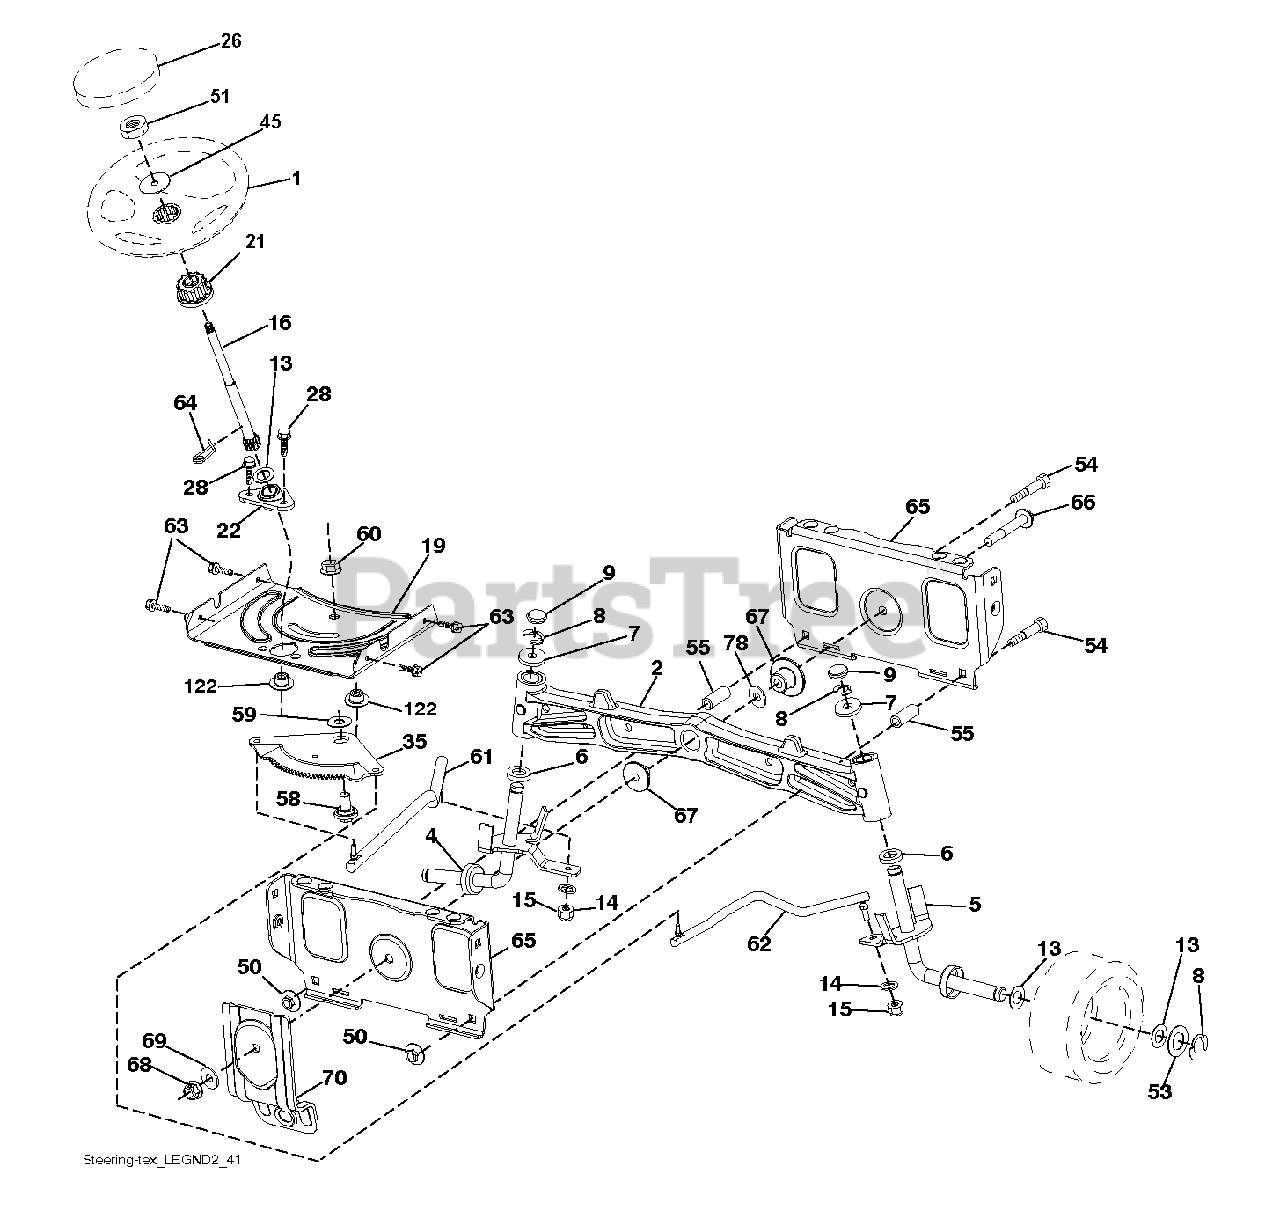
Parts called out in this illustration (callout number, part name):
1	WHEEL.STEER.HUSQ.SR.498.OVMLD
2	AXLE.CAST.IRON
4	SPINDLE.WELDED.LH.16"TEX
5	SPINDLE.WELDED.RH.16"TEX
6	THRUST WASHER
9	CAP.SPINDLE.BLACK
14	WASHER, LOCK 3/8
15	NUT CROWNLOCK 3/8-24
16	SHAFT, STEERING
19	PLATE.STEER.DDL.NLT/NG
21	ADAPTER, WHEEL STNG..
22	STEERING.SUPT.LOWER.
26	INSERT.CAP.WHL.STRG.HUSQ.PREM
28	SCREW, 3/8-16X3/4
35	GEAR.SECTOR.PLATE.DDL.
45	WASHER 9/16"ID, 2 3/8"OD
50	NUT LOCK FLG 3/8-16 UNC
51	NUT.HEX.1/2-20
53	WASHER.HARDENED
55	SPACER.BRACE.AXLE
58	BOLT.SHOULDER.SECTOR.P
59	WASHER.THURST.SECTOR.S
60	NUT FLANGE LOCK 5/8-11
61	DRAGLINK.LH.BALLSTUD.D
62	DRAGLINK.RH.BALLSTUD.D
63	SCREW
64	RETAINER.CLIP.SPRING.S
65	BRACE.AXLE.FRONT.NLT/N
66	BOLT HEX FGHD 7/16-14 X 3 SERR
67	BUSHING.PM.FRONT AXLE
68	NUT.LOCK.FLANGE.7/16
69	WASHER.1.5X.505X.118
70	BRKT.DECK.SUSPENSION.F
78	THRUST WASHER
122	CAP.GEAR.SECTOR.TEX
